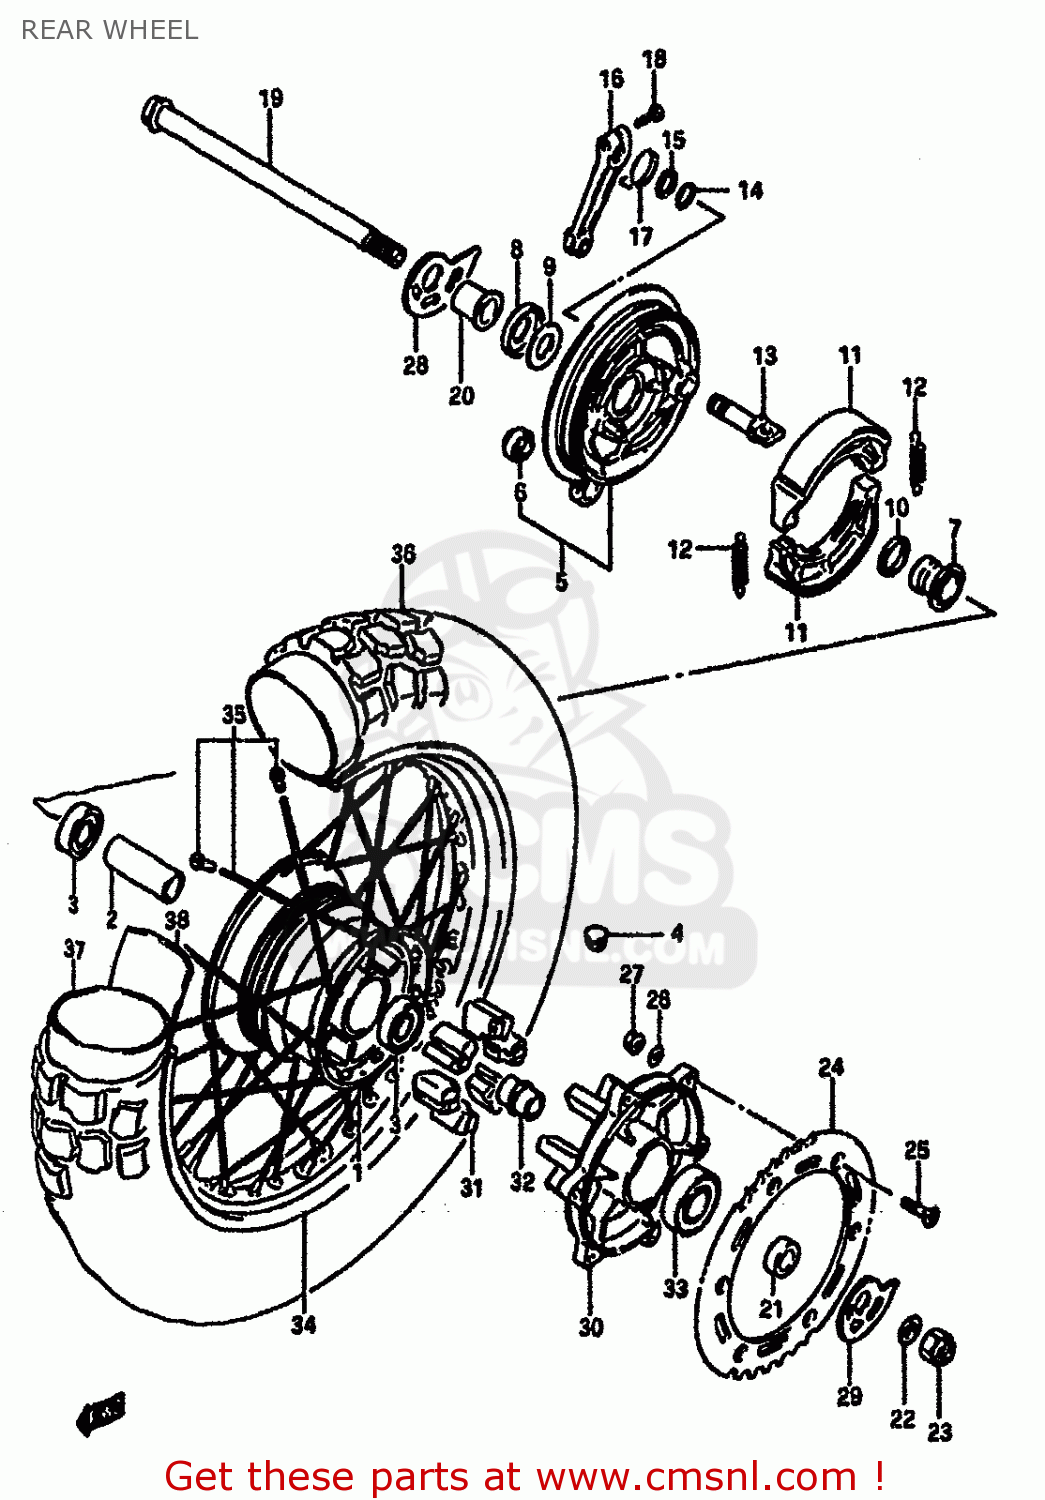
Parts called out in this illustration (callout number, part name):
1	DRUM,REAR HUB
2	SPACER (17.5X25X90)
3	BEARING
4	CAP(OD:12)
5	PANEL SET,REAR HUB
6	SPHERICAL BRNG,TORQUE LINK
7	SPACER,REAR BRAKE ANCHOR
8	CVR,RR BRAKE AHR PNL DUST SEAL
9	WASHER
10	SEAL,OIL(24X31X5)
11	SHOE,BRAKE
12	SPRING(L:34)
13	CAM,REAR BRAKE
14	O-RING
15	WASHER
16	LEVER,RR BRAKE CAM
17	SPRING
18	BOLT
19	AXLE,RR
20	SPACER,REAR AXLE,RIGHT
21	SPACER (17X33X11)
22	WASHER
23	NUT
24	SPROCKET,REAR
25	BOLT(8X30.5)
26	WASHER
27	NUT
28	ADJUSTER,CHAIN RH
29	ADJUSTER,CHAIN LH
30	DRUM,RR SPROCKET MOUNTING
31	CUSHION,REAR DRUM
32	RETAINER,RR SPROCKET DRUM
33	BEARING(25X52X15)
34	RIM,REAR WHEEL
35	SPOKE SET,REAR WHEEL
36	TIRE
37	TUBE ASSEMBLY,WHEEL,INNER
38	PROTECTOR,INNER TUBE
